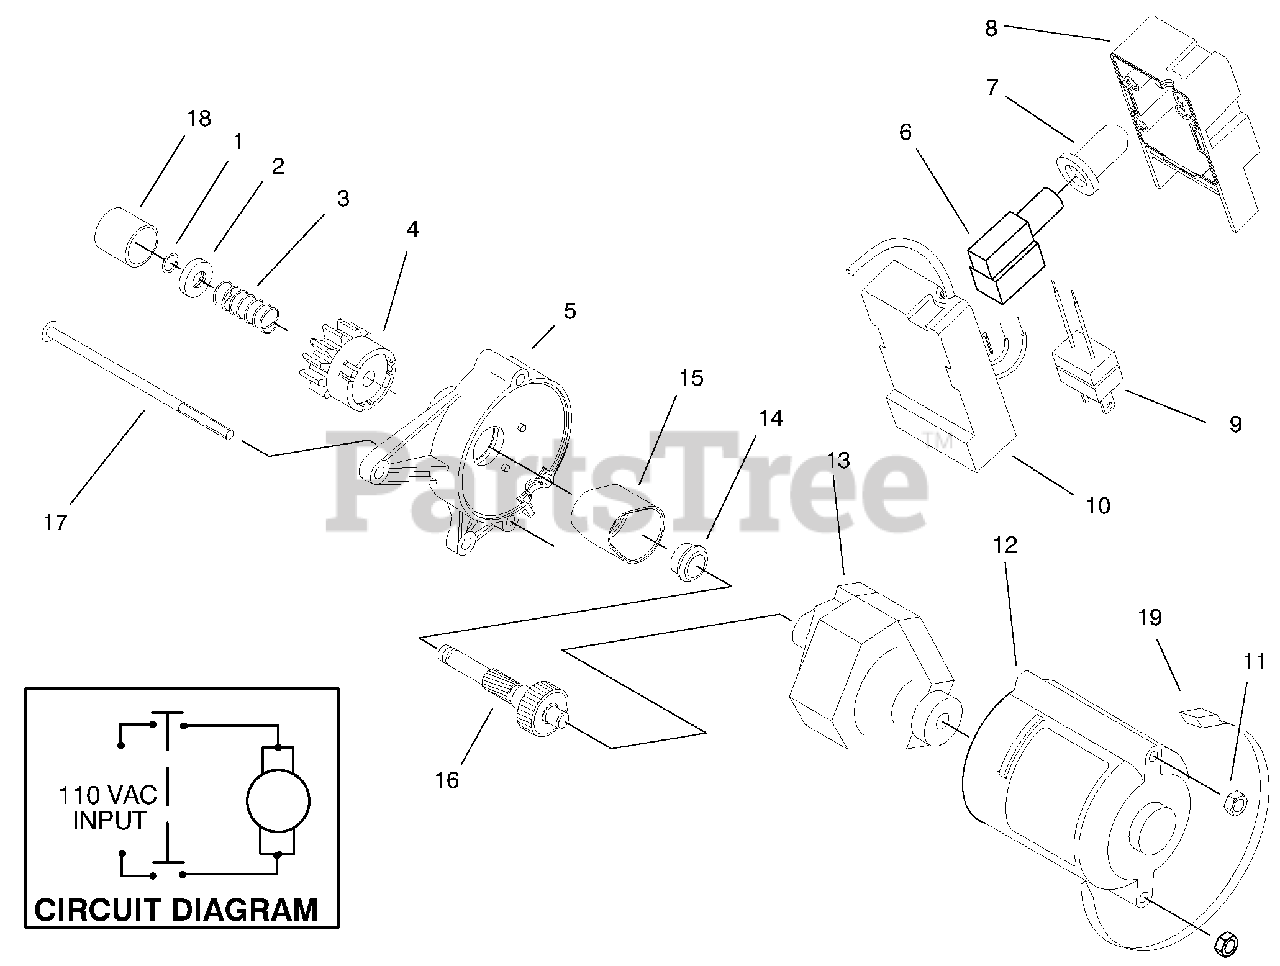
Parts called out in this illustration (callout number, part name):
1	Ring-Lock
2	Stop-Pinion
3	Spring-Anti Drift
4	Pinion Assembly
5	Housing-Upper Starter
6	Switch-Starter
7	Boot-Switch
8	Cap-Switch Housing
9	Plug-Power
10	Base-Switch Housing
11	Nut-Lock
12	Housing-Lower Starter
14	Bushing-Upper
15	Cover-Gear
16	Gear & Shaft Assembly
17	Screw-Machine
18	Cap-Pinion
19	Cable Tie
